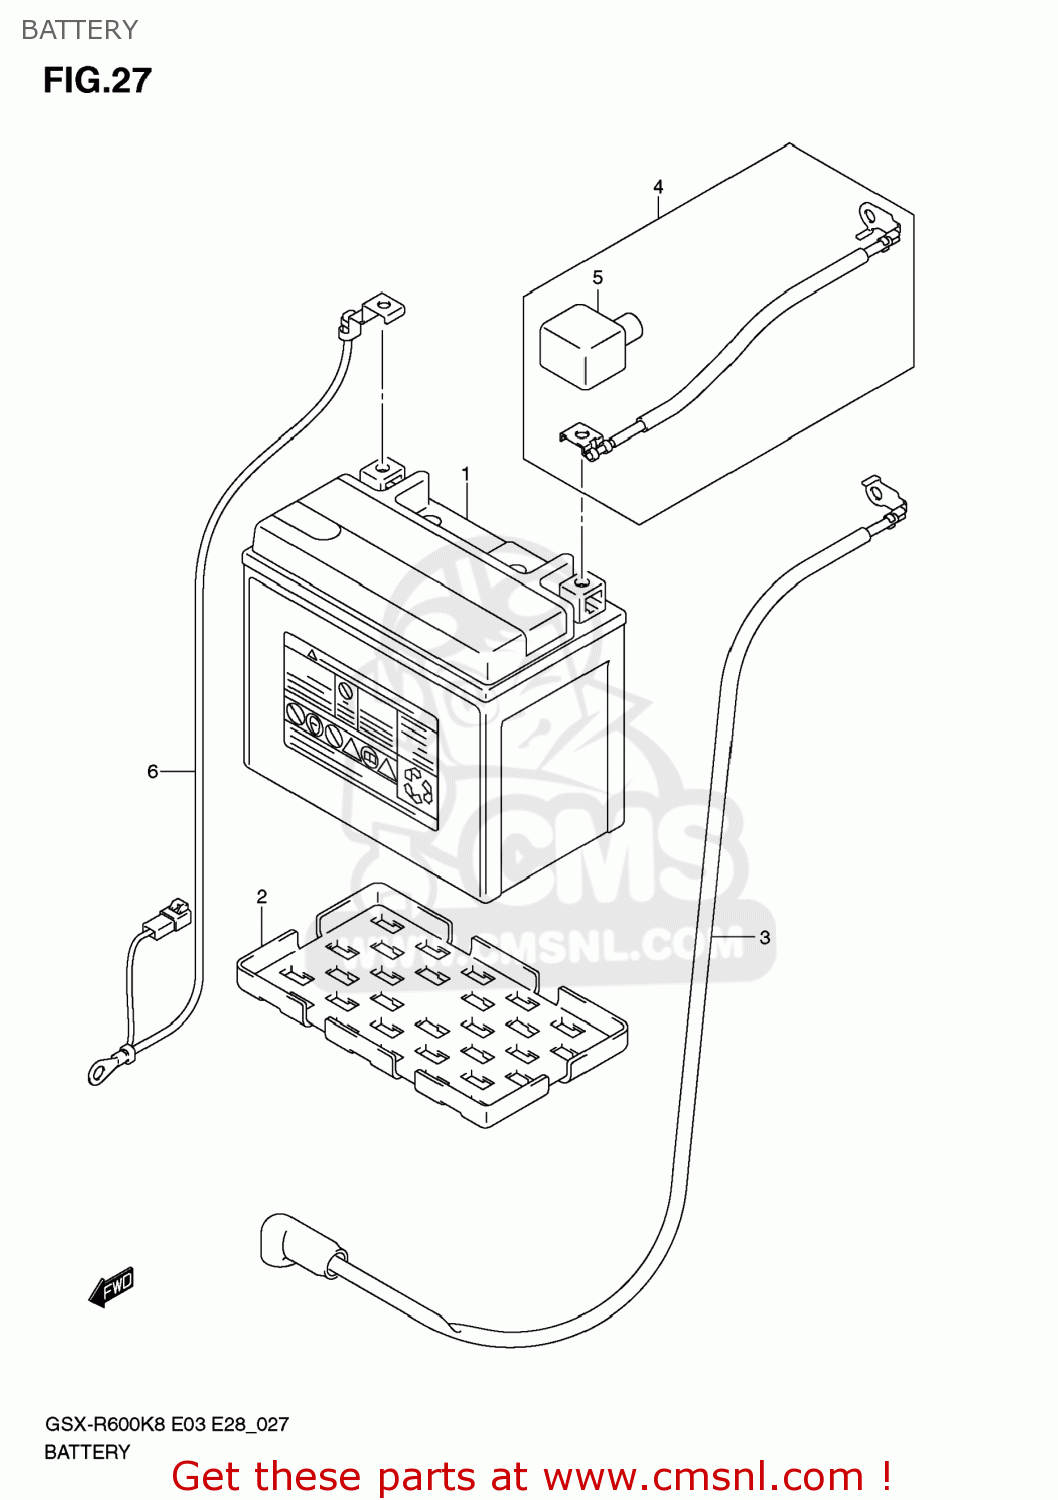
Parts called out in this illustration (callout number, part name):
1	BATTERY ASSEMBLY (12V) FTX
2	PROTECTOR,BATTERY
3	WIRE,STARTER MOTOR LEAD
4	WIRE,BATTERY PLUS LEAD
5	CAP,BATTERY PLUS
6	WIRE,BATTERY MINUS LEAD
